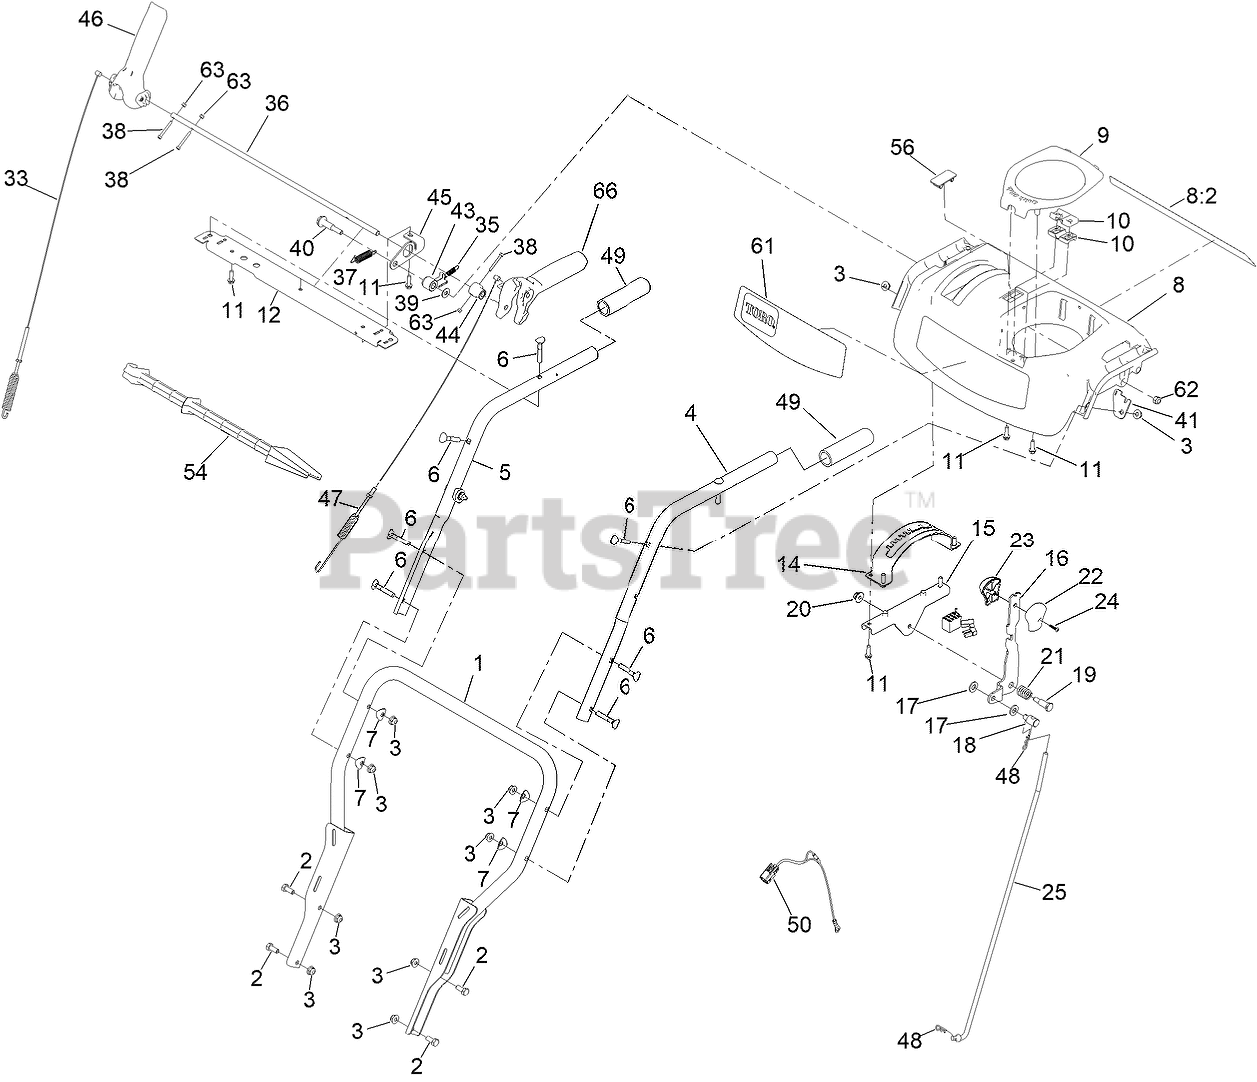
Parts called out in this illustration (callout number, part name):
1	LOWER HANDLE ASM
2	SCREW-HH
3	NUT-HF
4	HANDLE-UPPER, LH
5	HANDLE-UPPER, RH
6	SCREW-HANDLE
7	WASHER-CUP
8	CONTROL PANEL ASSEMBLY
8:2	DECAL-SAFETY
9	COVER-QUICKSTICK
10	SUPPORT-ROD
11	SCREW-PLASTITE, HWH
12	BRACE-CONSOLE
14	GATE-SHIFT
15	BRACKET-SHIFT
16	SELECTOR-SPEED
17	WASHER-FLAT
18	TRUNNION-ROD
19	SCREW-SHOULDER, HH
20	NUT-HF
21	SPRING-COMPRESSION
22	KNOB-SHIFT, LH
23	KNOB-SHIFT, RH
24	SCREW-PPH
25	ROD-SHIFT
33	CABLE-AUGER
35	SPRING-LOCKOUT, HANDLE
36	ROD-LOCKOUT
37	SPRING-RETURN, LEVER
38	SCREW-HSH,SPL
39	WASHER-FLAT
40	SCREW-SHOULDER
41	PLATE-SPRING
43	LATCH, LOCKOUT
44	CAM-LOCKOUT
45	BRACKET-INTERLOCK
46	LEVER-CONTROL
47	CABLE-TRACTION
48	PIN-HAIR
49	GRIP-HANDLE
50	HARNESS-WIRE, LED
54	STICK-CLEANOUT
56	PLUG-HOLE
61	DECAL-CONSOLE
62	NUT-HEX
63	NUT-LOCK ROHS
66	LEVER-CONTROL
